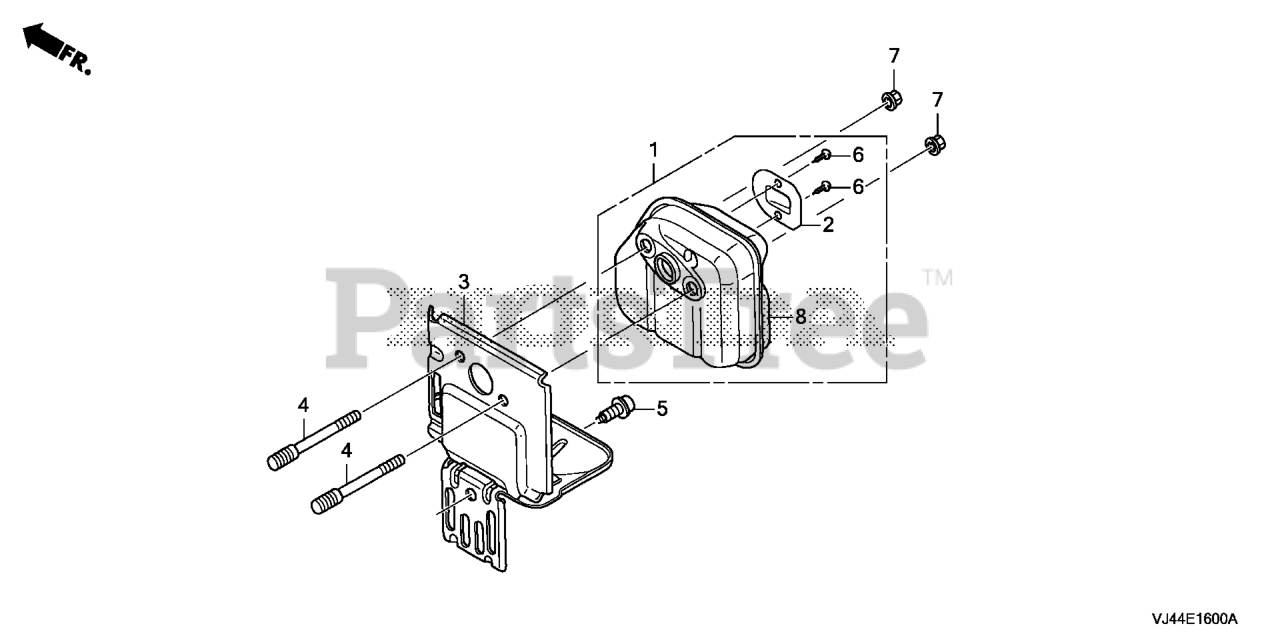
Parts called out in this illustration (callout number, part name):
1	MUFFLER
2	ARRESTER, SPARK
3	GUIDE, AIR EX.
4	BOLT, STUD (5X52)
5	BOLT, SOCKET (5X10) (CT)
5	BOLT, SOCKET (5X10)
6	SCREW, TAPPING (4X6) (TO INSTALL OPTIONAL SPARK ARRESTER)
7	NUT, SELF-LOCK (5MM)
